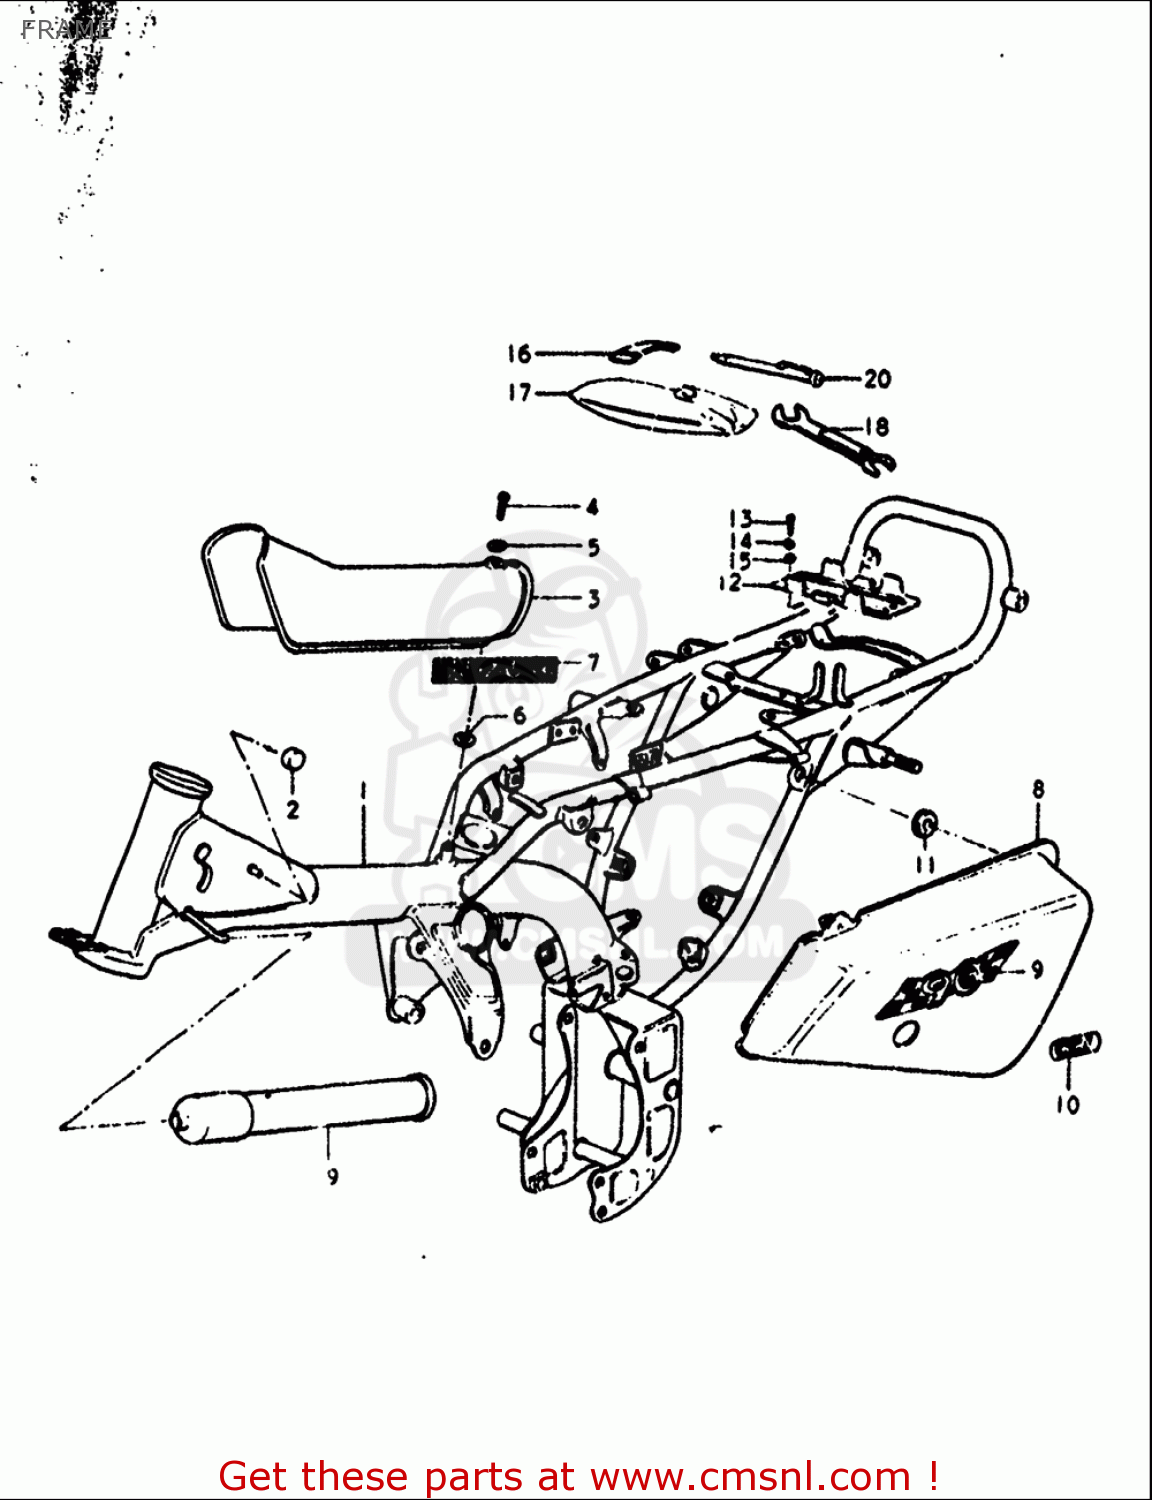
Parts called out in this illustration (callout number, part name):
2	CUSHION
4	SCREW
7	EMBLEM,SUB FUEL TANK
10	EMBLEM,CCIS
11	CUSHION
13	SCREW
14	WASHER,LOCK
15	WASHER
16	BAND
17	TOOL ASSY
